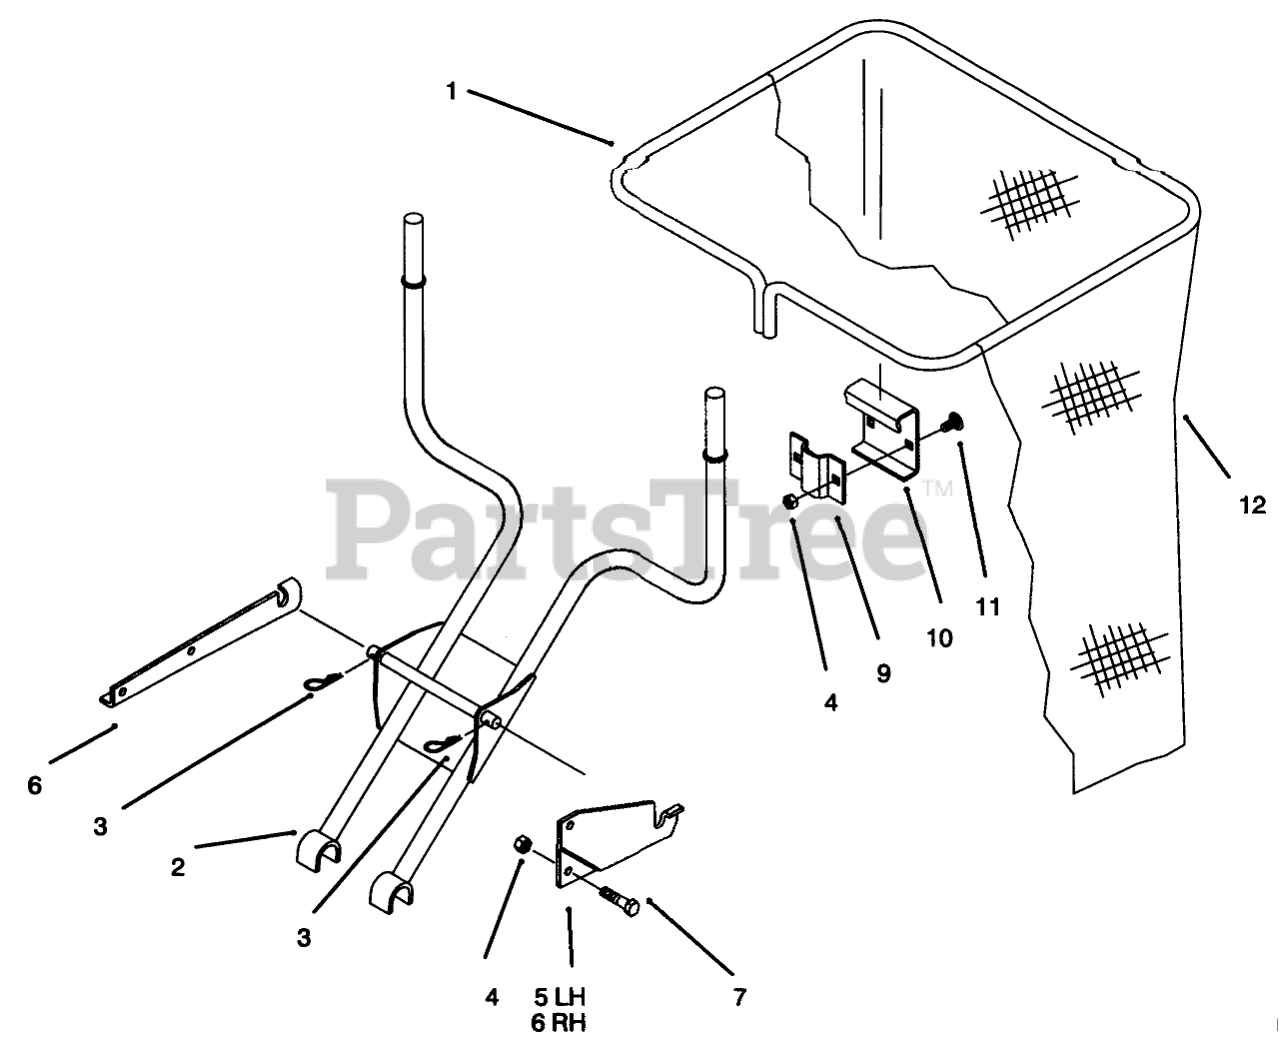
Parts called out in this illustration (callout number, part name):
1	Bag Frame
2	WLDMT-QUICK ATTAC B
3	PIN-COTTER, HAIR
4	NUT-LOCK, NI
5	SUPPORT-BAGGER L. B
6	SUPPORT-BAGGER R. B
7	SCREW-HH
9	Clamp
10	Bag Hanger
11	BOLT-CARR
12	BAG-DEPTH
